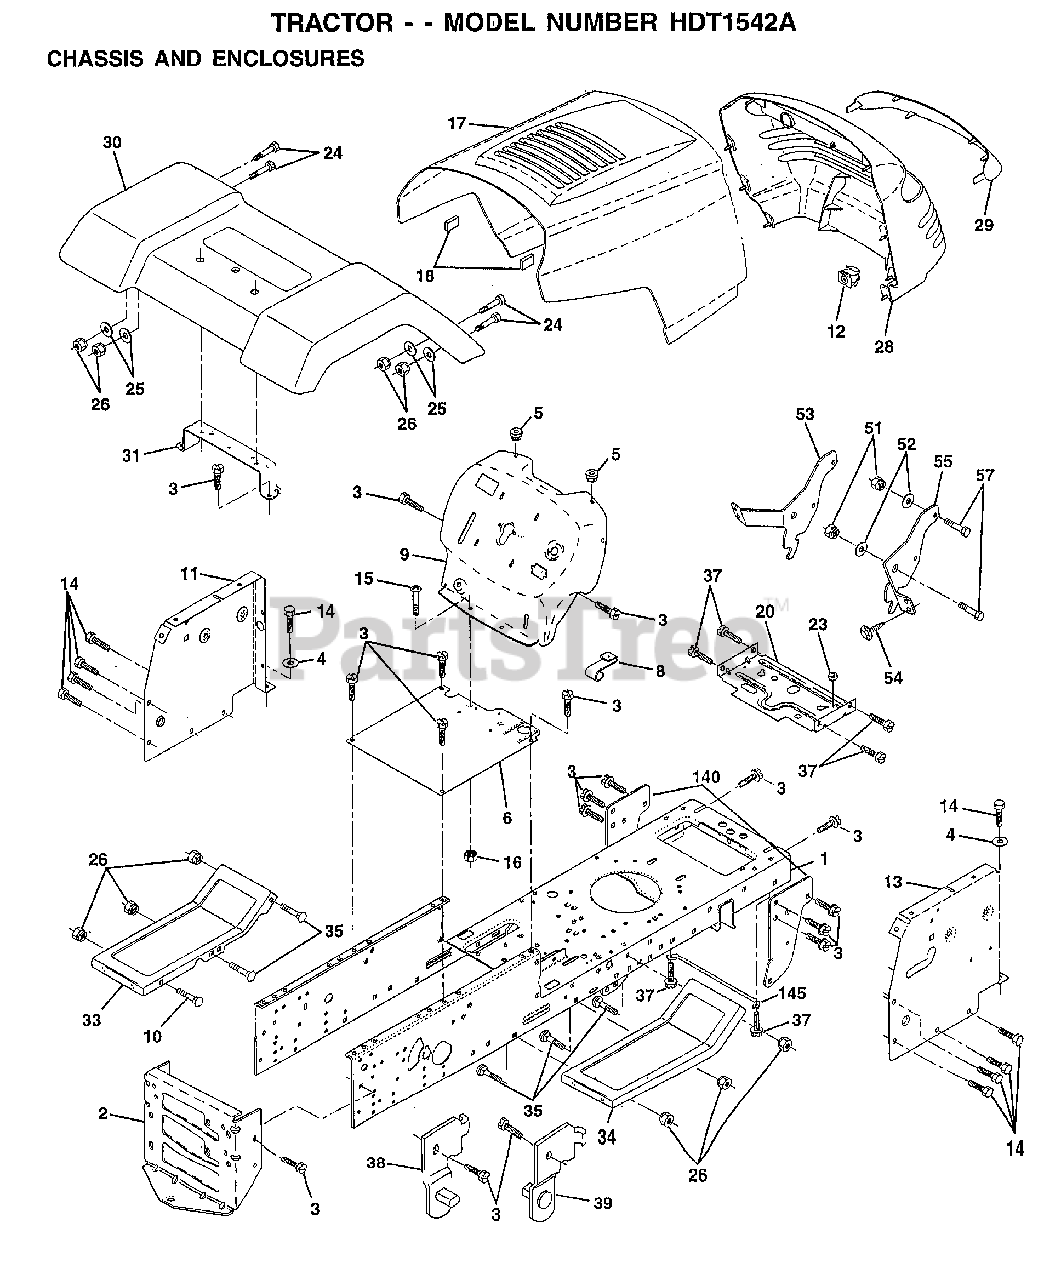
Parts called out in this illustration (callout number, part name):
1	CHASSIS.STAMPING
3	SCREW
4	WASHER
5	BUMPER-HOOD/DASH
6	SADDLE
8	CLIP.RETAINER
9	DASH SILKSCREEN
11	"PANEL-DASH,LH"
12	CLIP.TINNERMAN
13	PANEL.ASM.SLKSCR.DASH.RH
14	SCREW LT
15	SCREW
17	"HOOD W/TRIM,MS428"
20	"PLATE-MTG,BATT/FU"
24	BOLT
25	WASHER
26	NUT
28	GRILLE-MS428
29	LENS.GRILLE.PRIVATE LABEL
30	FENDER ASM.
31	BRKT FENDER
33	FOOTREST LH
34	FOOTREST RH
35	BOLT
37	SCREW LT
38	BRACKET ASM LH
39	BRACKET ASM RH
51	NUT
52	WASHER
53	BRACKET.GRILLE.LH
54	SCREW.HEX.WS.HD
55	BRACKET.GRILLE.RH
140	BRKT SUSPENSION
145	"ROD POVOT,CHASSIS"
